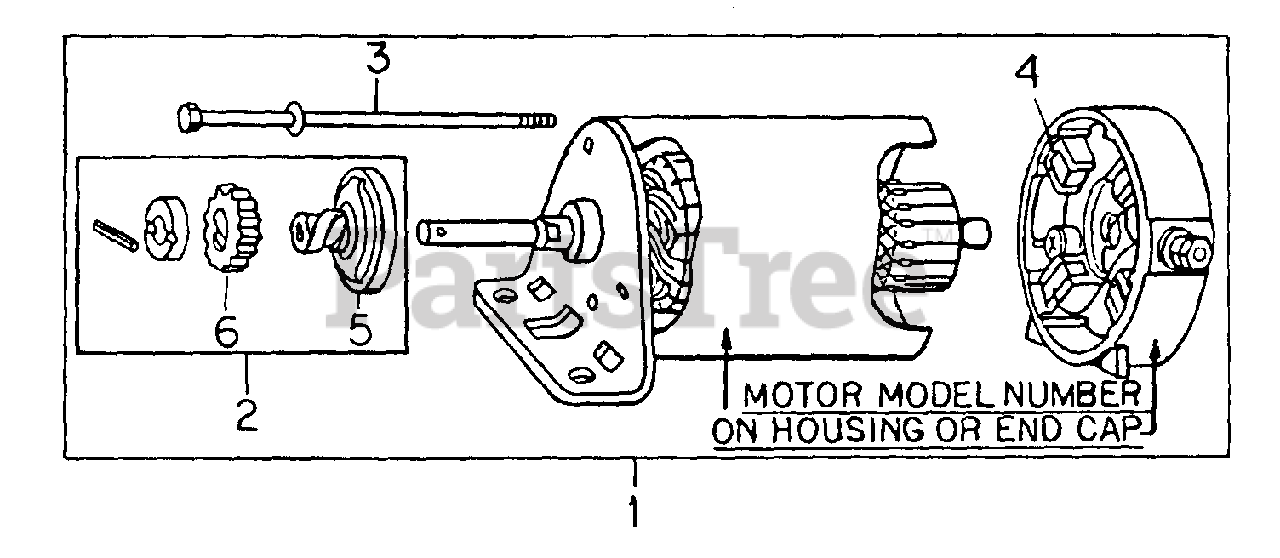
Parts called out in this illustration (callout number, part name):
1	MOTOR ASSY, STARTER
2	DRIVE, MOTOR
3	BOLT, 1/4-20 X 4 ZND HEX-HD MACH
4	BRUSH KIT
5	CLUTCH ASSY, STARTER
6	GEAR, STARTER DRIVE
